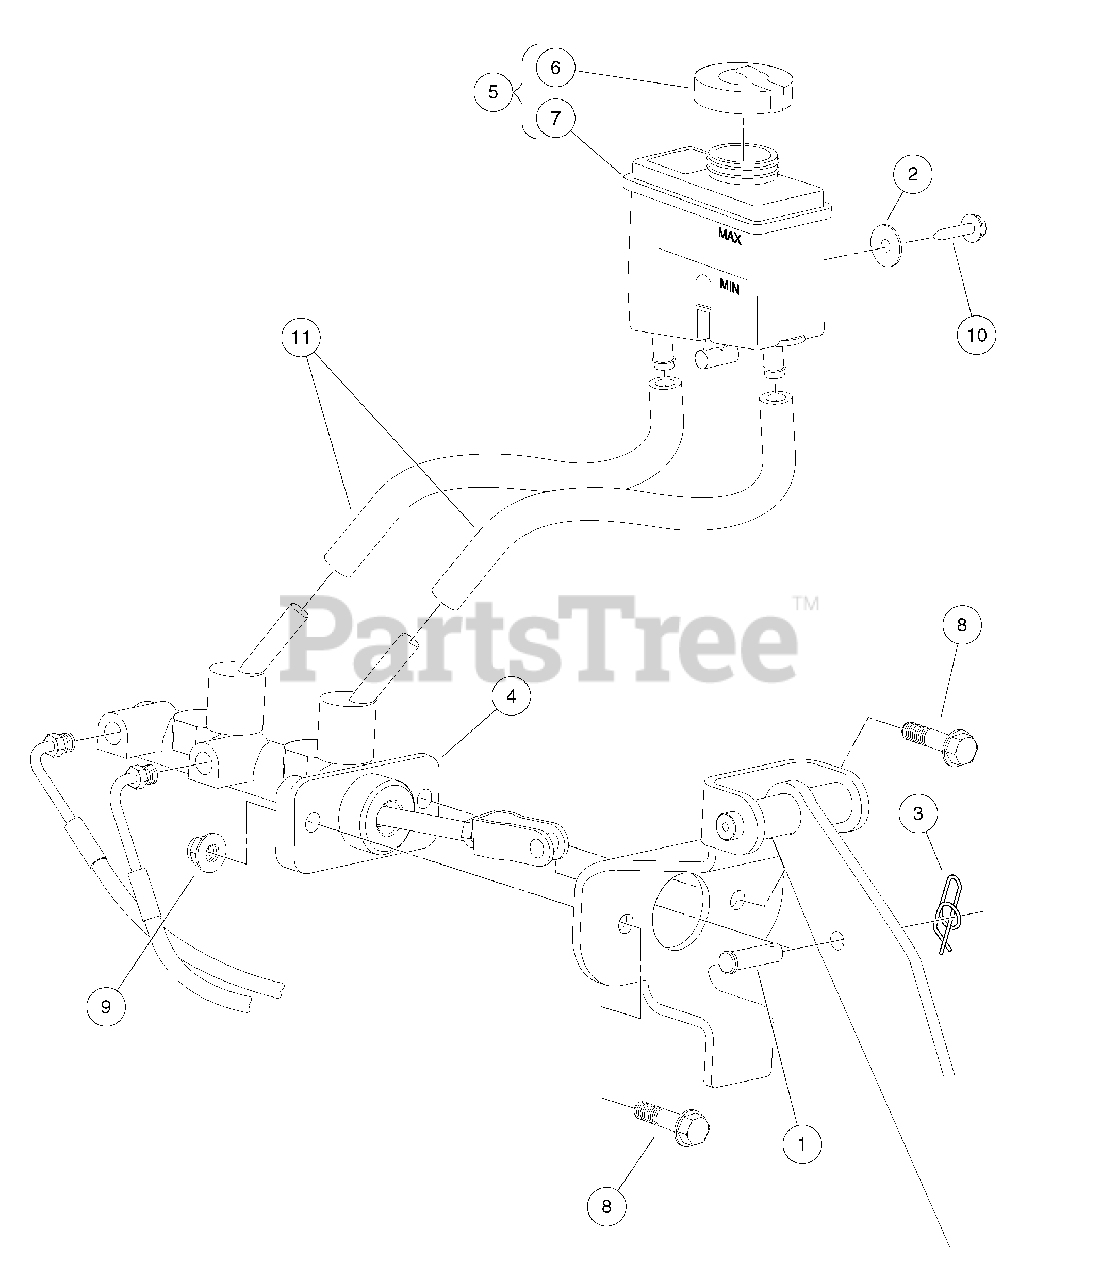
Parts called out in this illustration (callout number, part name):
1	Clevis Pin, 5/16 X 1
2	Washer, 1/4" Type B Flat
4	Cylinder, Master, Tandem
5	Assembly, Reservoir, Remote
6	Filler Cap Asm
7	Reservoir, Brake Fluid, Without Cap
8	Bolt Flanged Head, M8 X 1.25 X 35
9	Lock Nut, Flg M8 X 1.25 Nylon
10	Screw, #10x3.50 Ab Thd, Hex Hd
11	Hose, Reservoir, Brake Fluid
